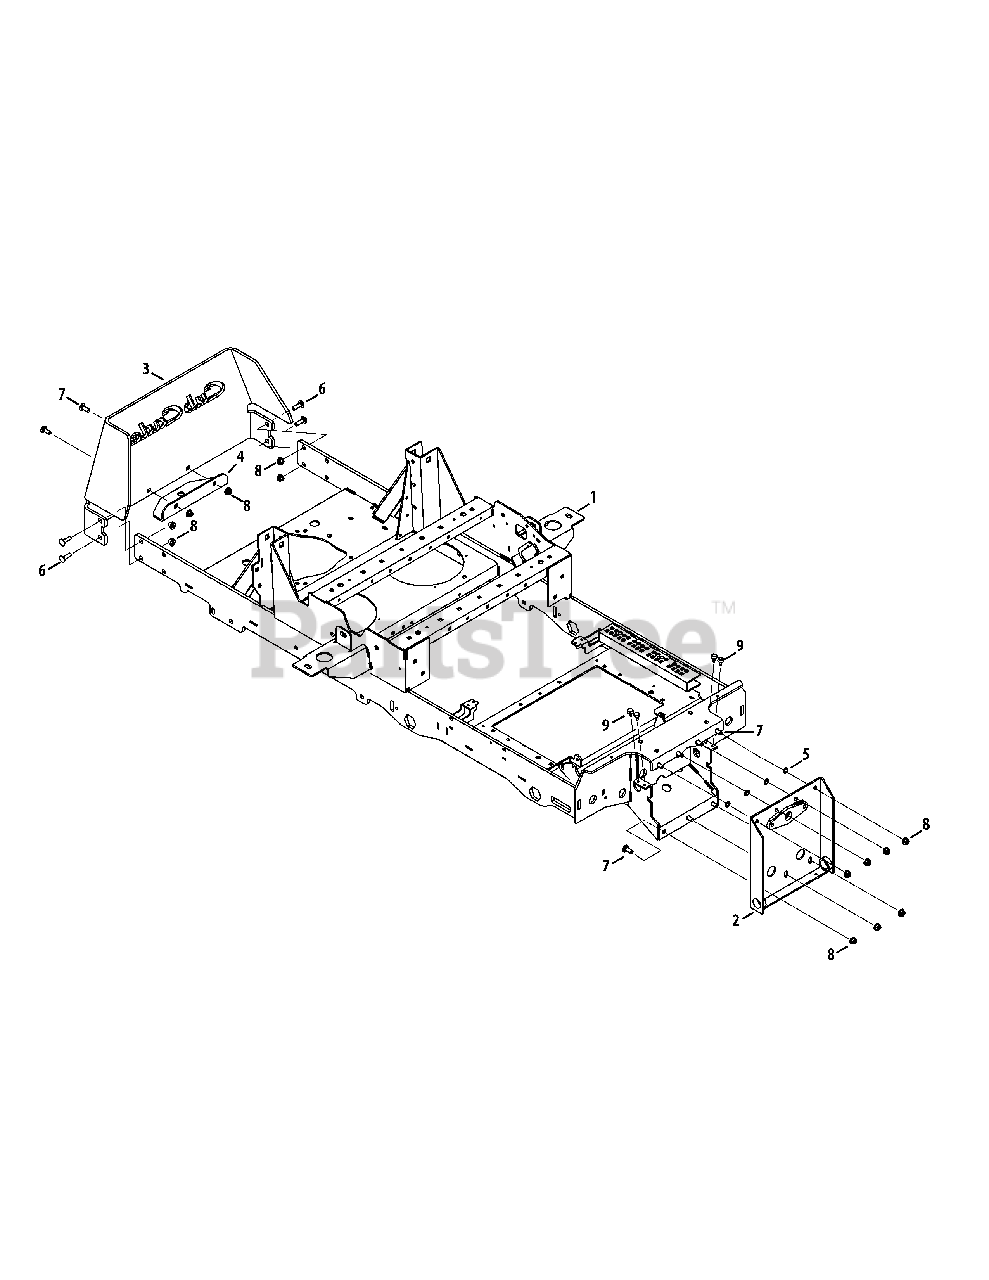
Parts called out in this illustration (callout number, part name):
1	Frame Assembly
2	Front Axle Bracket Assembly
5	Push Nut, 3/8
6	Carriage Bolt, 3/8-16 x 1.25
7	Carriage Bolt, 3/8-16 x 1.00
8	Nylock Nut, 3/8-16
9	Bumper, .62 Dia. x .3
